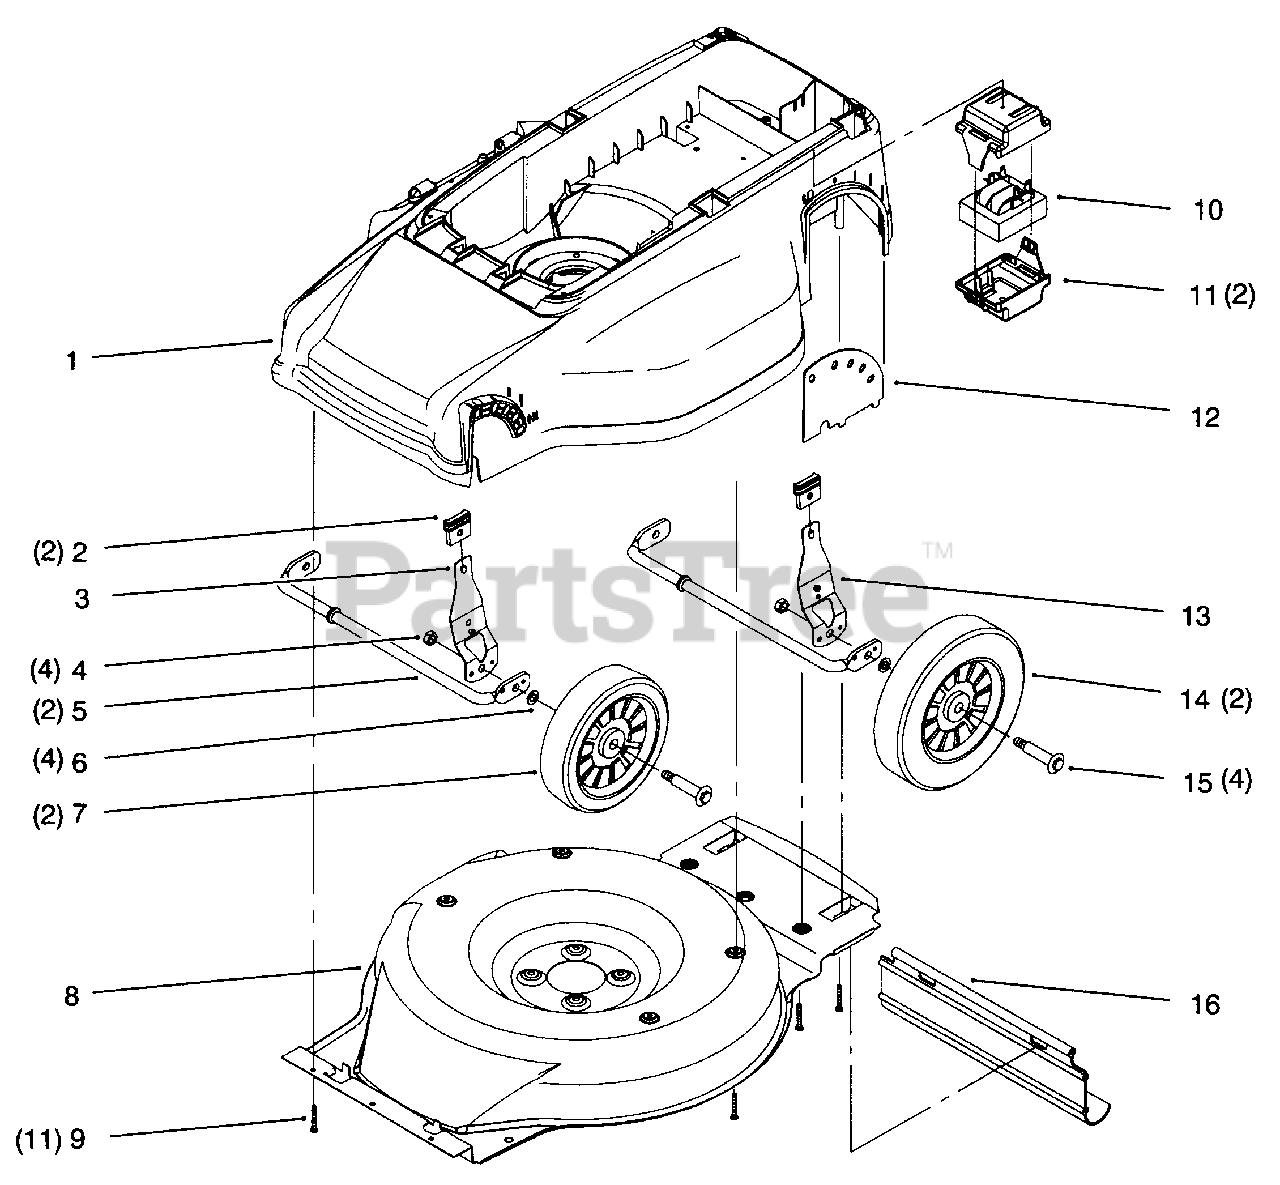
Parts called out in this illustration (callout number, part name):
2	Knob-Height Adjust
3	ASM-Front HOC Lever
4	Nut-Lock
7	ASM-Wheel
8	ASM-Liner
9	Screw-PPH
10	Transformer
11	Housing-Transformer
12	Plate-HOC
13	ASM-Rear HOC Lever
14	ASM-Wheel
15	Bolt-Shoulder
16	Trailing Shield
